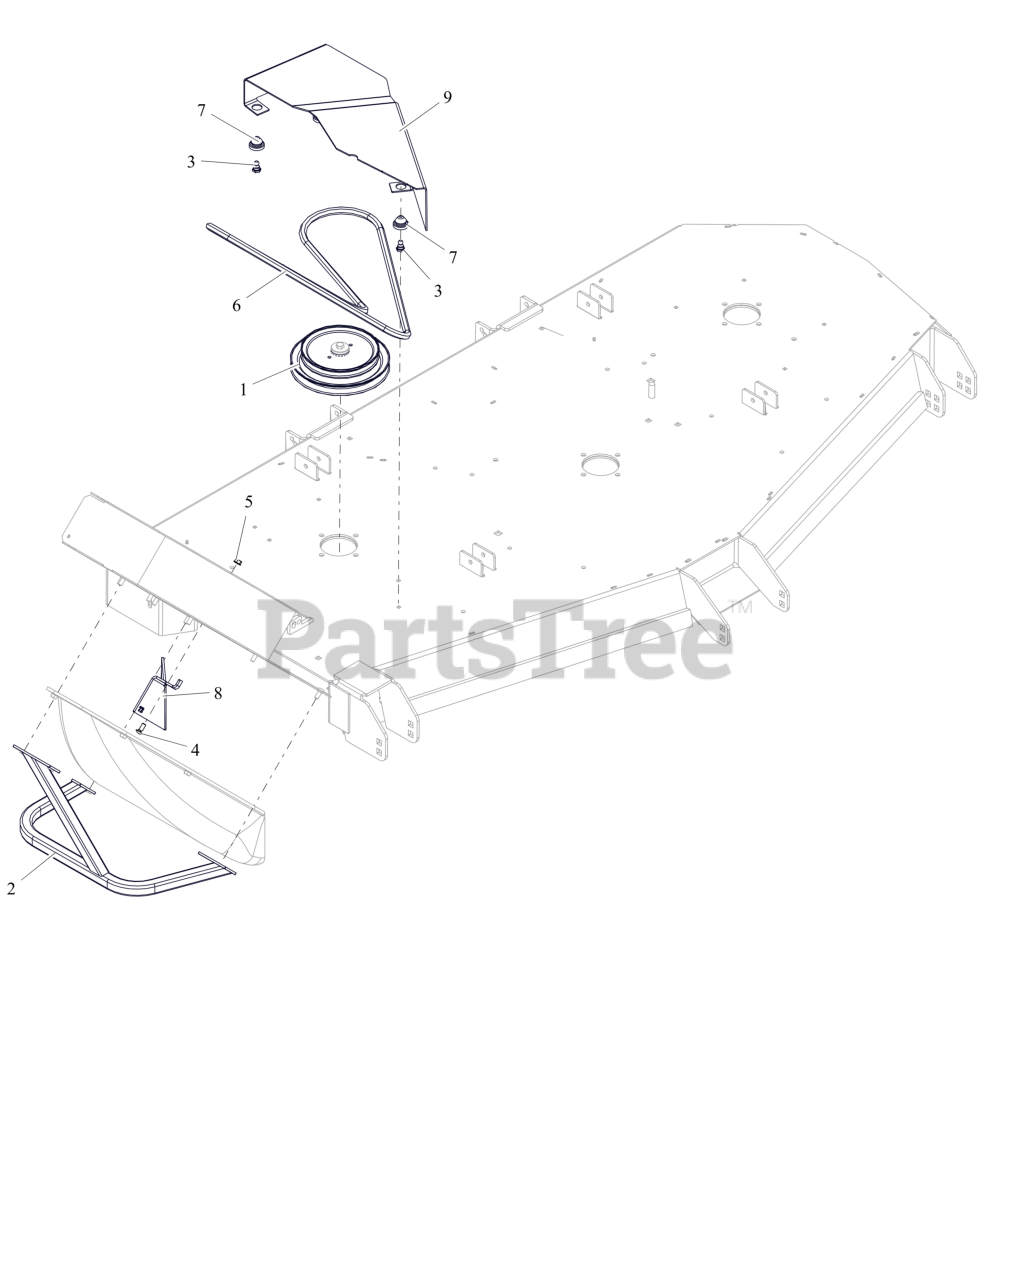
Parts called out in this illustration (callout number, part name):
1	SHV-DBL 1.00"IDX8.25"&6.50"OD
2	WLDMT, BLOWER GUARD (BLACK)
3	STUD, BALL FEMALE .250-20 THREAD
4	BLT, RHSSN.31-18X.750 G5 ZCC
5	NUT,LK-CTR-FLG .31-18 GF ZCC
6	HEX BELT, HAA SECTION
7	COUPLING, RUBBER PUSH-IN
8	BRKT, PT600 72" BAGGER DISCH (BLACK)
9	GUARD, RH 72" BLOWER DECK BELT (BLACK)
